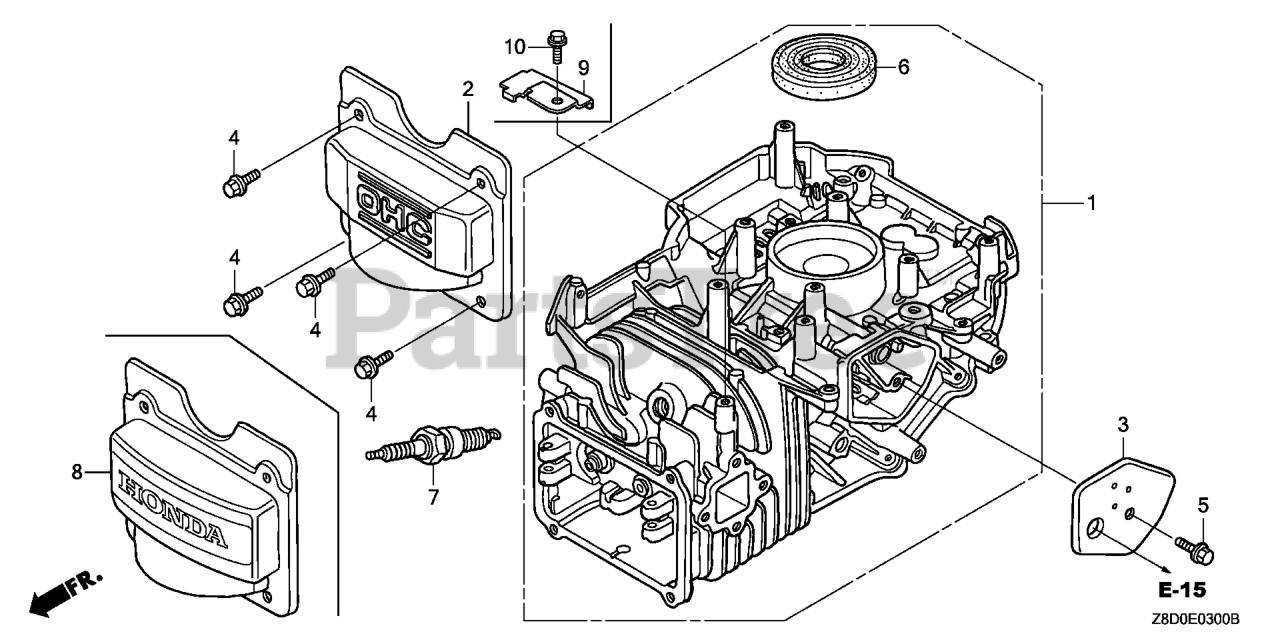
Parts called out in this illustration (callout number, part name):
1	BARREL ASSY,CYLN
3	COVER, BREATHER (Honda Code 5580006). (BREATHER VALVE ASSY.)
4	BOLT, FLANGE (6X12) (CT200)
5	BOLT, FLANGE (6X14)
6	OIL SEAL (25.4X62X6)
7	SPARK PLUG (BPR6ES) (NGK)
8	COVER, HEAD
